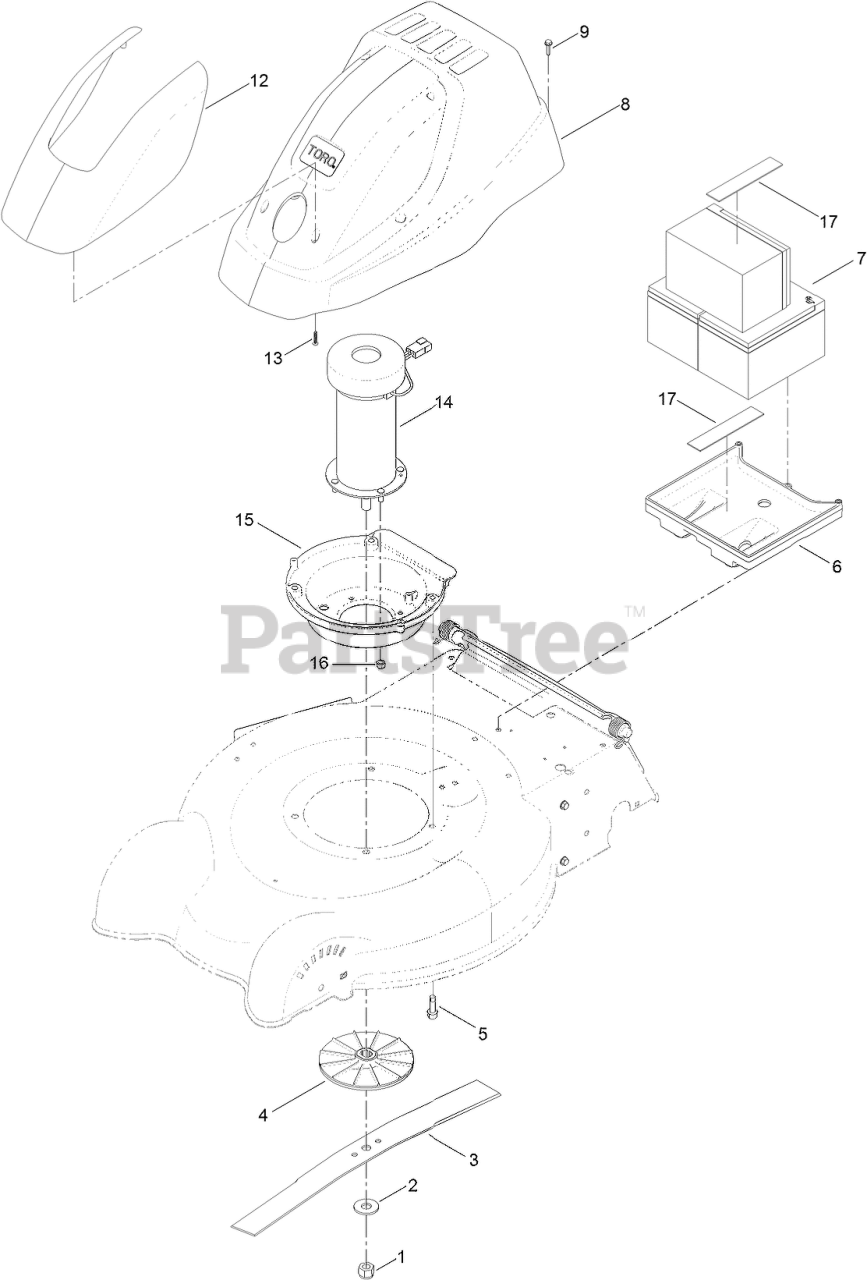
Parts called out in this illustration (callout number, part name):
1	NUT-HEX
2	WASHER-FLAT
3	BLADE-20 INCH
4	FAN MOTOR ASM
5	SCREW-TAPTITE
6	TRAY-BATTERY
7	BATTERY ASM
8	SHROUD ASM
9	SCREW-HWH
12	COVER-SHROUD
13	SCREW-PPH
14	MOTOR-36V
15	BASE-MOTOR
16	NUT-LOCK, NI
17	TAPE-FOAM, 2 SIDED
